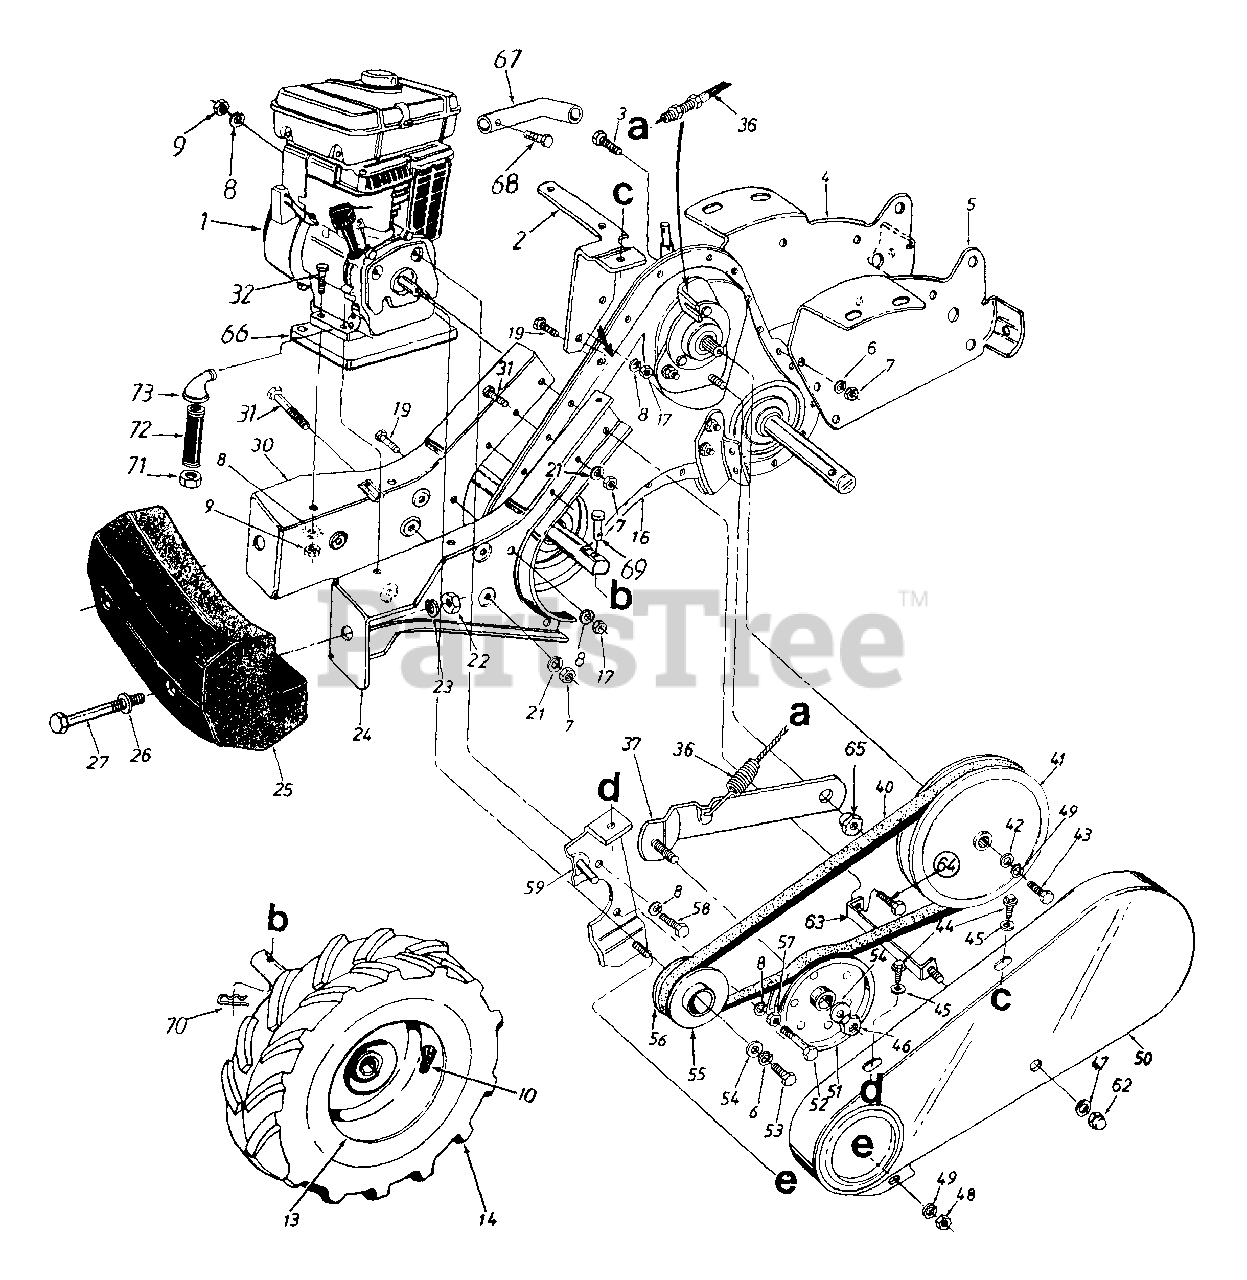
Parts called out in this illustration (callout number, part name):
1	Engine
4	Tine Shield Mtg. Brkt. - R.H.
7	Hex Nut 3/8-16 Thd.
8	L-Wash. 5/16" I.D.
9	Hex Nut 5/16-18" Thd.
10	Air Valve
16	Gear Case Ass'y. Comp.
17	Hex Nut 5/16-18 Thd.
19	Hex Bolt 5/16-18 x .75" Lg.
21	L-Wash. 3/8" I.D. - H.D.
22	Hex Nut 1/2-13 Thd.
23	L-Wash. 1/2" I.D.
26	Fl-Wash. .510" I.D. x 1.0"
27	Hex Bolt 1/2-13 x 5.00" Lg.
32	Hex Bolt 5/16-18 x 2.75"
36	Clutch Control Cable 46" Lg.
37	Idler Bracket Ass'y.
40	V-Belt
41	Fl-Pulley 8" O.D.
42	Fl-Wash. 1/4" I.D. x .93" O.D.
43	Hex Bolt 1/4-28 x .75" Lg.
44	Hex Wash. Hd. S-Tap Scr. 1/4-20 x .50" Lg.
45	Fl-Wash. .281" I.D. x .625"
46	Hex Cent. L-Nut 3/8-24 Thd.
47	Fl-Wash. .266" I.D. x .625" O.D.
48	Hex Nut 1/4-20 Thd.
49	L-Wash. 1/4" I.D.
51	Fl-Idler w/Flanges 3.75" O.D.
52	Hex Bolt 5/16-24 x 1.75"
53	Hex Bolt 3/8-24 x 1.00" Lg.
54	Fl-Wash. 3/8" I.D. x 1.00"
55	Outer Engine Pulley Half
56	Inner Engine Pulley Half
57	Hex Nut 5/16-24 Thd.
58	Hex Bolt 5/16-24 x .62" Lg.
59	Belt Keeper Ass'y.
62	Hex Cap Nut 1/4-28 Thd.
63	Belt Cover Brkt. Ass'y.
64	Hex Bolt 5/16-18 x 1" Lg. (Gr. 5)
65	Shld. Nut
66	Engine Spacer Block
67	Outlet Pipe
68	Hex Wash. Hd. AB-Tap Scr. #8 x .5" Lg.
69	Clevis Pin
70	Hairpin Clip
71	Oil Cap 1/4" NPT
72	Drain Pipe 1/4" NPT
73	Street Elbow 1/4" NPT
